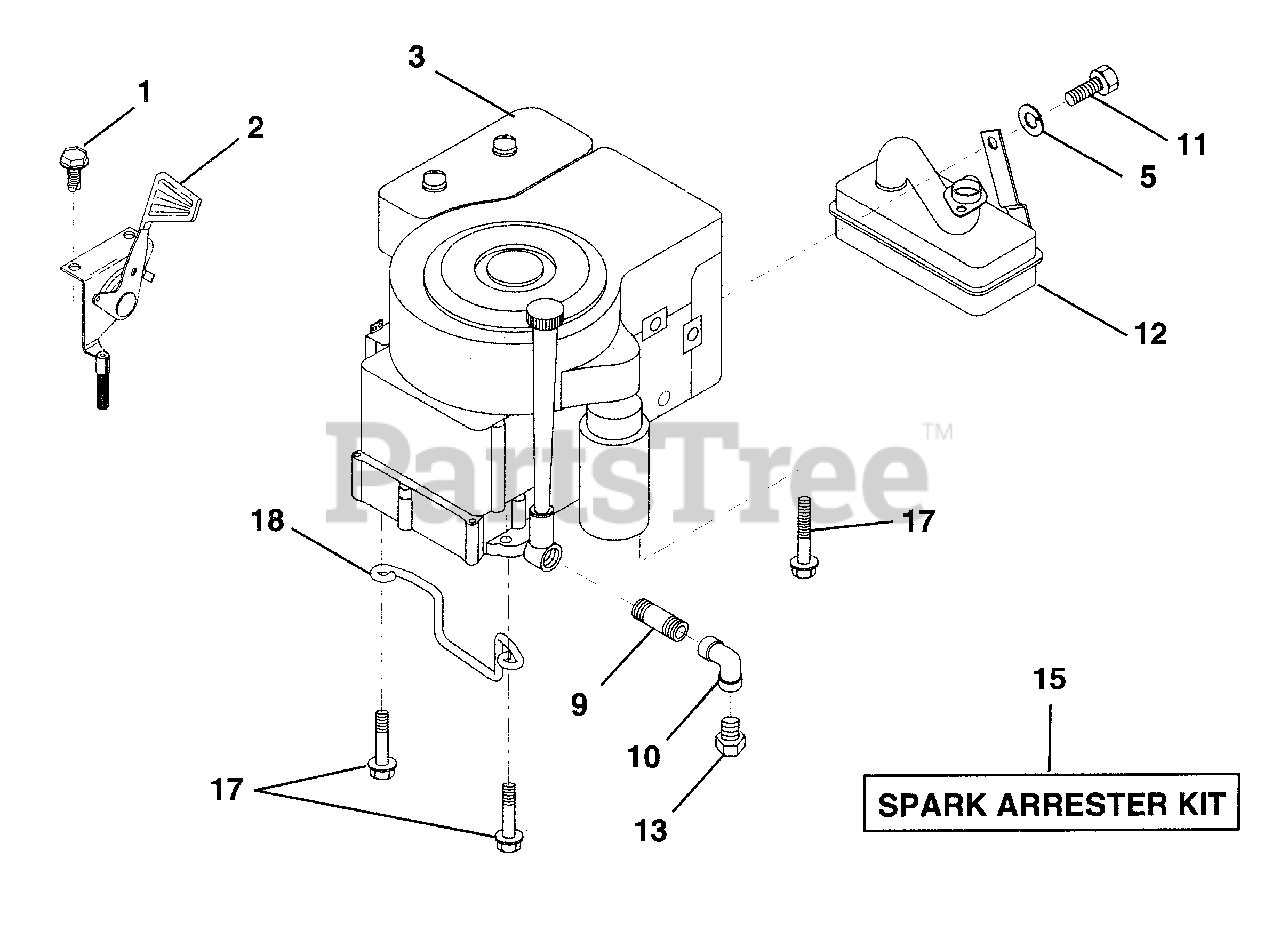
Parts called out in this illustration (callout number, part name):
1	Screw, Hex Head, Thread Cutting 1/4-20 x 1/2
2	Control, Throttle
5	Washer, Lock, Heavy Helical Spring 5/16
9	Nipple, Pipe 3/8 N.P.T. x 3-1/2
10	Elbow, Standard 90°.
11	Bolt, Hex Head, Fin. 5/16-18 x 1/2
13	Plug, Oil Drain
15	Arrester, Spark
17	Bolt, Hex Head
18	Keeper, Ground Drive Belt
